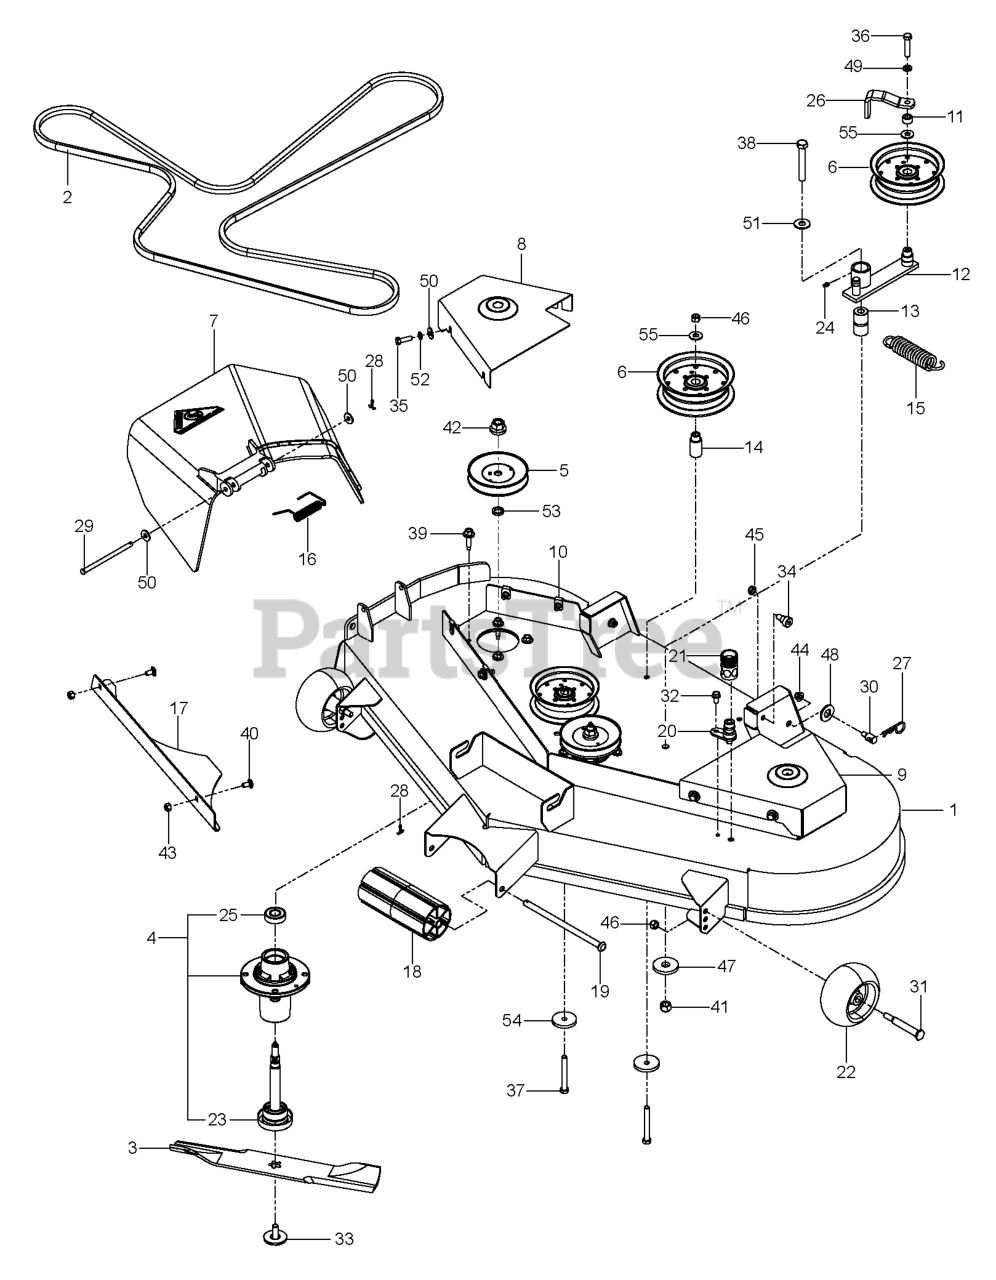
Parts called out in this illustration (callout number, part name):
1	DECK.48".TRI-FORCE.W/DECALS.OR
2	BELT, DECK
3	BLADE, 16-1/4"
4	MANDREL.DECK.ASSEMBLY
5	MANDREL PULLEY
6	PULLEY, IDLER
7	DISCHARGE CHUTE 48"
8	BELT SHIELD - R.H. ORANGE
9	BELT SHIELD - L.H. ORANGE
10	U-CLIP 5/16-18 NUT RETAINER
13	PIVOT BUSHING
14	IDLER BUSHING
16	SPRING - TORSION
17	CONFINEMENT PLATE 48" BLK
18	NOSE ROLLER 48"
19	ROD.ROLLER.NOSE.NARROW.48"
20	PORT.WASHOUT
21	COUPLING.QUICK CONNECT
22	GAUGE WHEEL
23	GREASABLE MANDREL SHAFT
24	ZERK
25	BEARING, BALL
26	GUIDE, BELT
27	HAIRPIN #4
28	RP_COTTER PIN 1/8 X 3/4
29	PIN-CLEVIS 5/16 DIA X 5.19 ZD
30	STUD.FASTNER.W/ANTI-ROTATE
31	SHOULDER BOLT 1/2X2-5/8 ZD SPE
32	BOLT 1/4-20 X 1/2 HWST
33	BLADE BOLT ASSY-7/16" TB REPL
34	SB 3/8-16 X 3/8 SKT HD ZD
35	HCS 5/16C X 1
36	HCS 3/8-16 X 1 3/4 GR5
37	HCS 3/8C X 3
38	HCS 1/2C X 3 1/4
39	WASHER HEAD SCREW
40	CARRIAGE BOLT 5/16C X 5/8"
41	NUT 1/2-13 HEX NYLOC ZD
42	LOCKNUT - 9/16
43	NUT 5/16 NYLOC
44	5/16-18 NYLOC FLANGE NUT
45	NUT HEX 3/8-16 NYLON, THIN
46	NUT 3/8-16 NYLOC
47	WASHER, SUPPORT
48	WASHER 5/8 FLAT
49	SLW 3/8 STD
50	WASHER 5/16 FLAT
51	WASHER 1/2 FLAT
52	WASHER.LOCK.HVY.HLCL.SPR.5/16
53	WASHER-SPACER
54	SPINDLE WASHER
55	WASHER 3/8 FLAT
